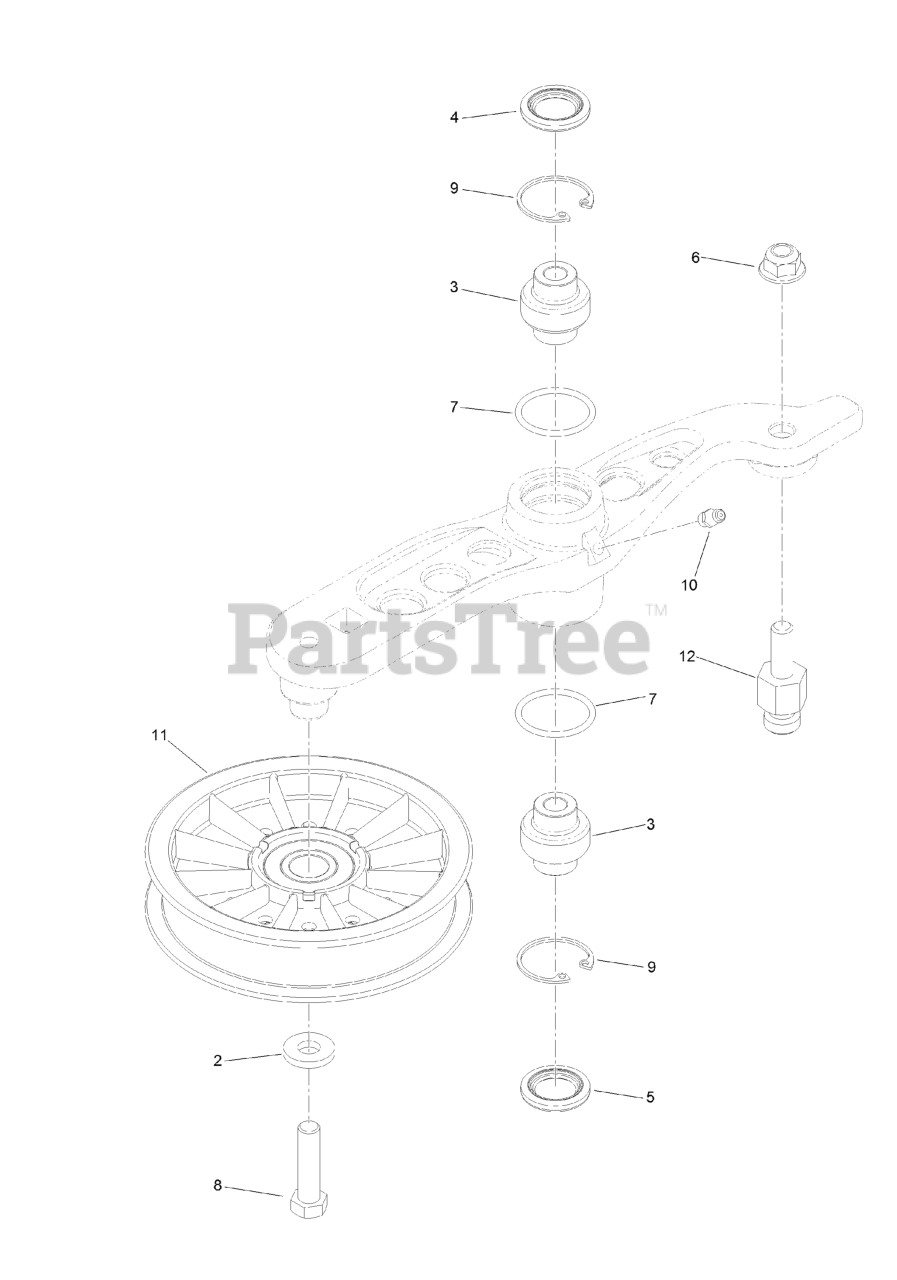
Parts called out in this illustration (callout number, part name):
3	BEARING-SPHERICAL
4	SEAL-LIP, DOUBLE
5	SEAL-LIP, SINGLE
6	Nut-Nyloc 3/8-16 Flg
8	SCREW-HH
9	RING-SNAP
10	FITTING-GREASE
11	PULLEY-IDLER
12	PIN-ANCHOR, SPRING
